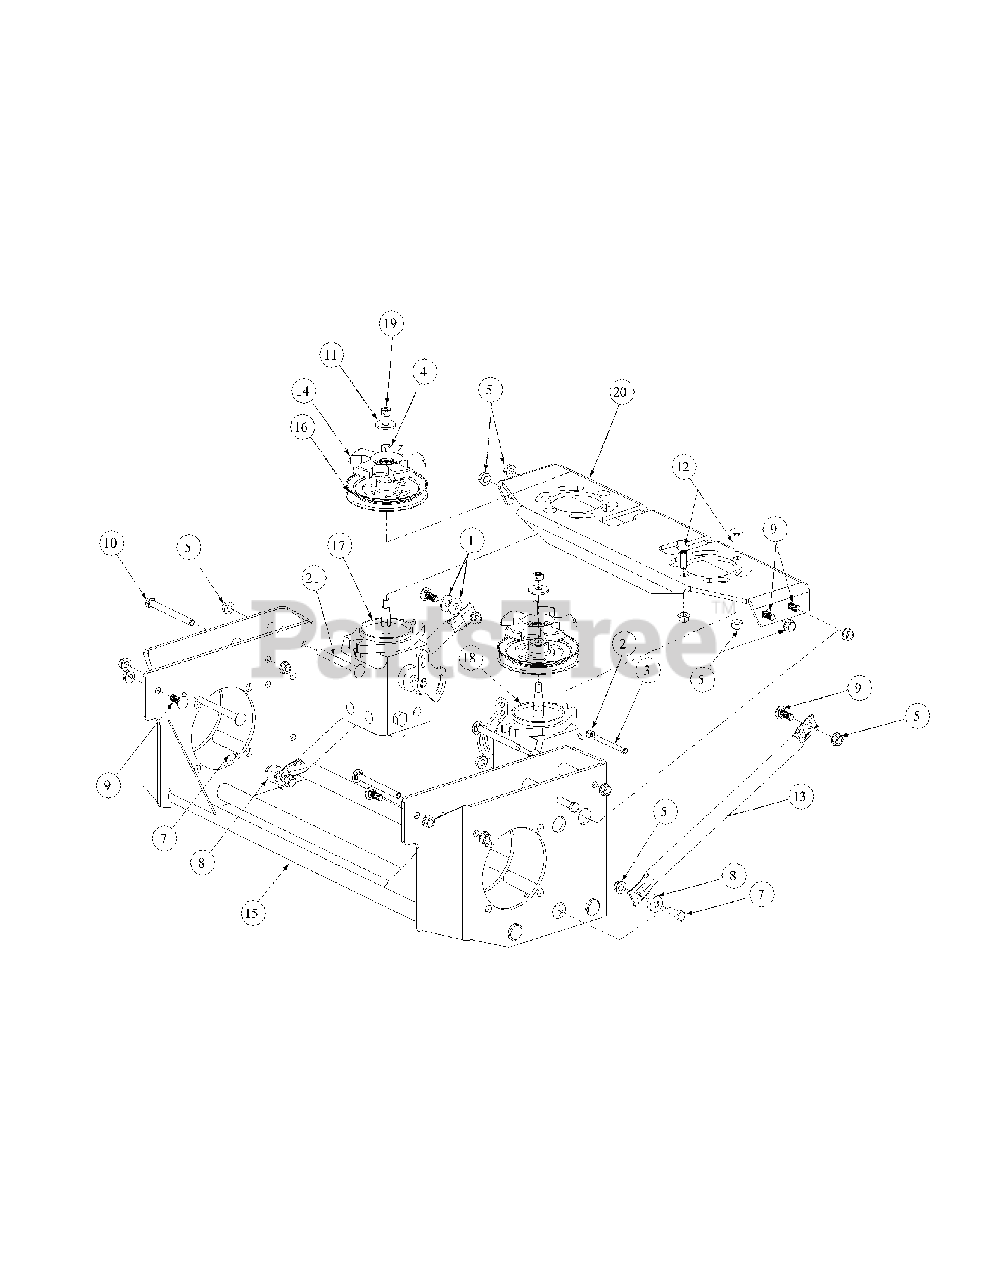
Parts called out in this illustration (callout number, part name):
1	Washer lock 3/8 zinc
2	Lock Nut, Nylon Insert, 1/4-20
3	Socket Head Cap Screw, 1/4-20 x 2-1/2
4	Key, 3/16" x 7/8"
5	Flange Lock Hex Nut, 3/8-16
7	Hex Cap Screw, 3/8 -16 x 1.25
8	Spacer, .406 ID x 1.00 OD x .38
9	Carriage Bolt, 3/8-16 x 1
10	Hex Cap Screw, 3/8-16 x 3.75
11	Flat Washer, .411 x 1.25 x .100
12	Carriage Screw, 3/8-16 x 1.25
14	Hydro Pulley Fan
15	Hydro Motor Frame Assembly
16	Hydro Pump Pulley
17	Hydro Pump, LH
18	Hydro Pump, RH
19	Hex Nut, 3/8-24
20	Hydro Pump Mount
21	Carriage Bolt, 3/8-16 x 4"
